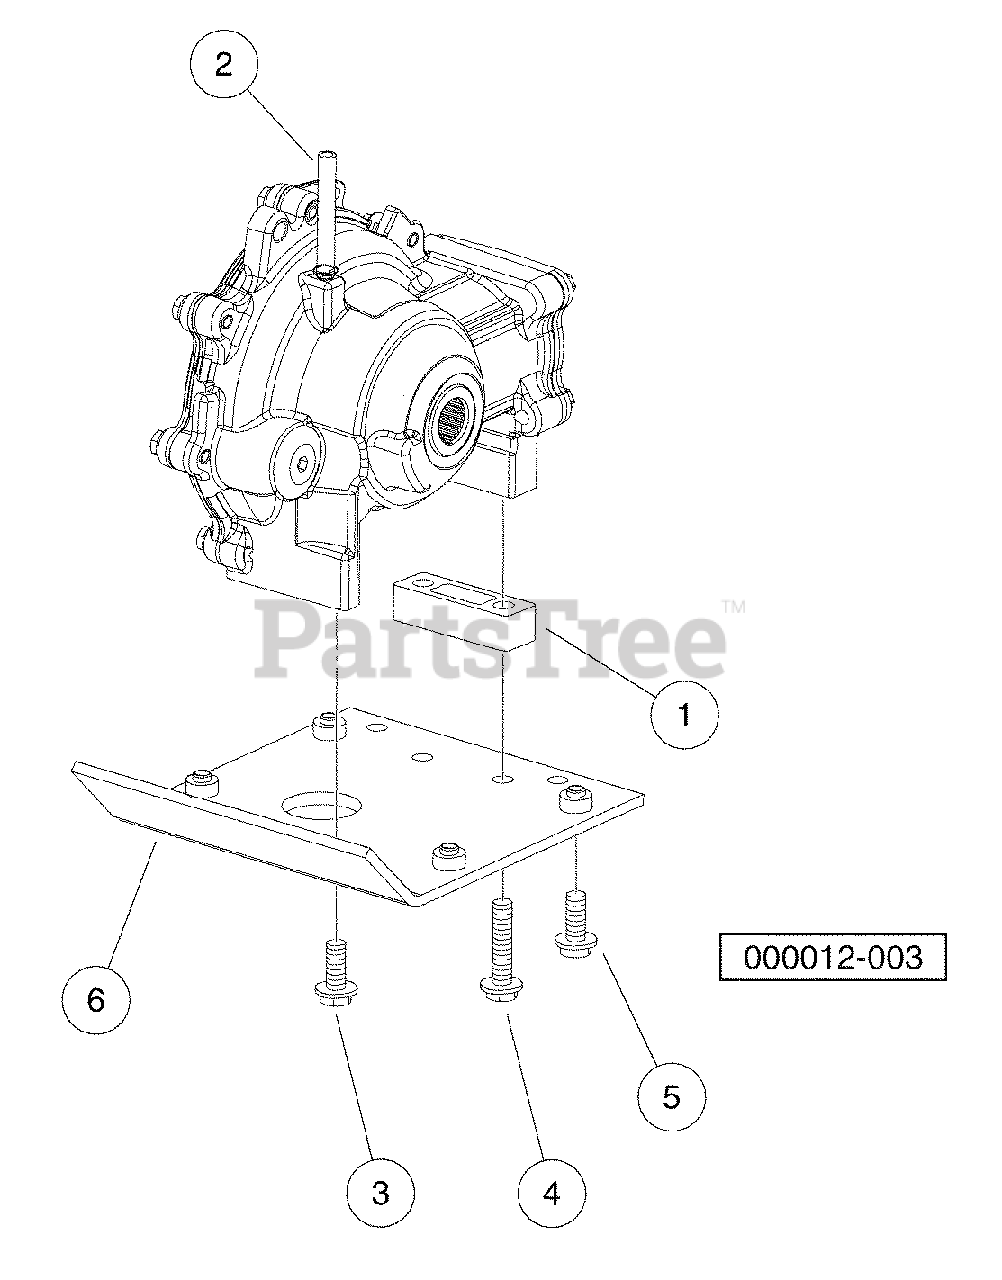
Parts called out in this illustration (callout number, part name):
1	Spacer Block, Diff
2	Hose, Vent, Front Diff
3	Bolt Flanged Head, 3/8-16x1.0 with Loctite
4	Bolt Flanged Head, 3/8-16x1.500 with Loctite
5	Bolt, Flange Head, M10 X 1.5 X 25
6	Asm, Mount, Diff Plate
